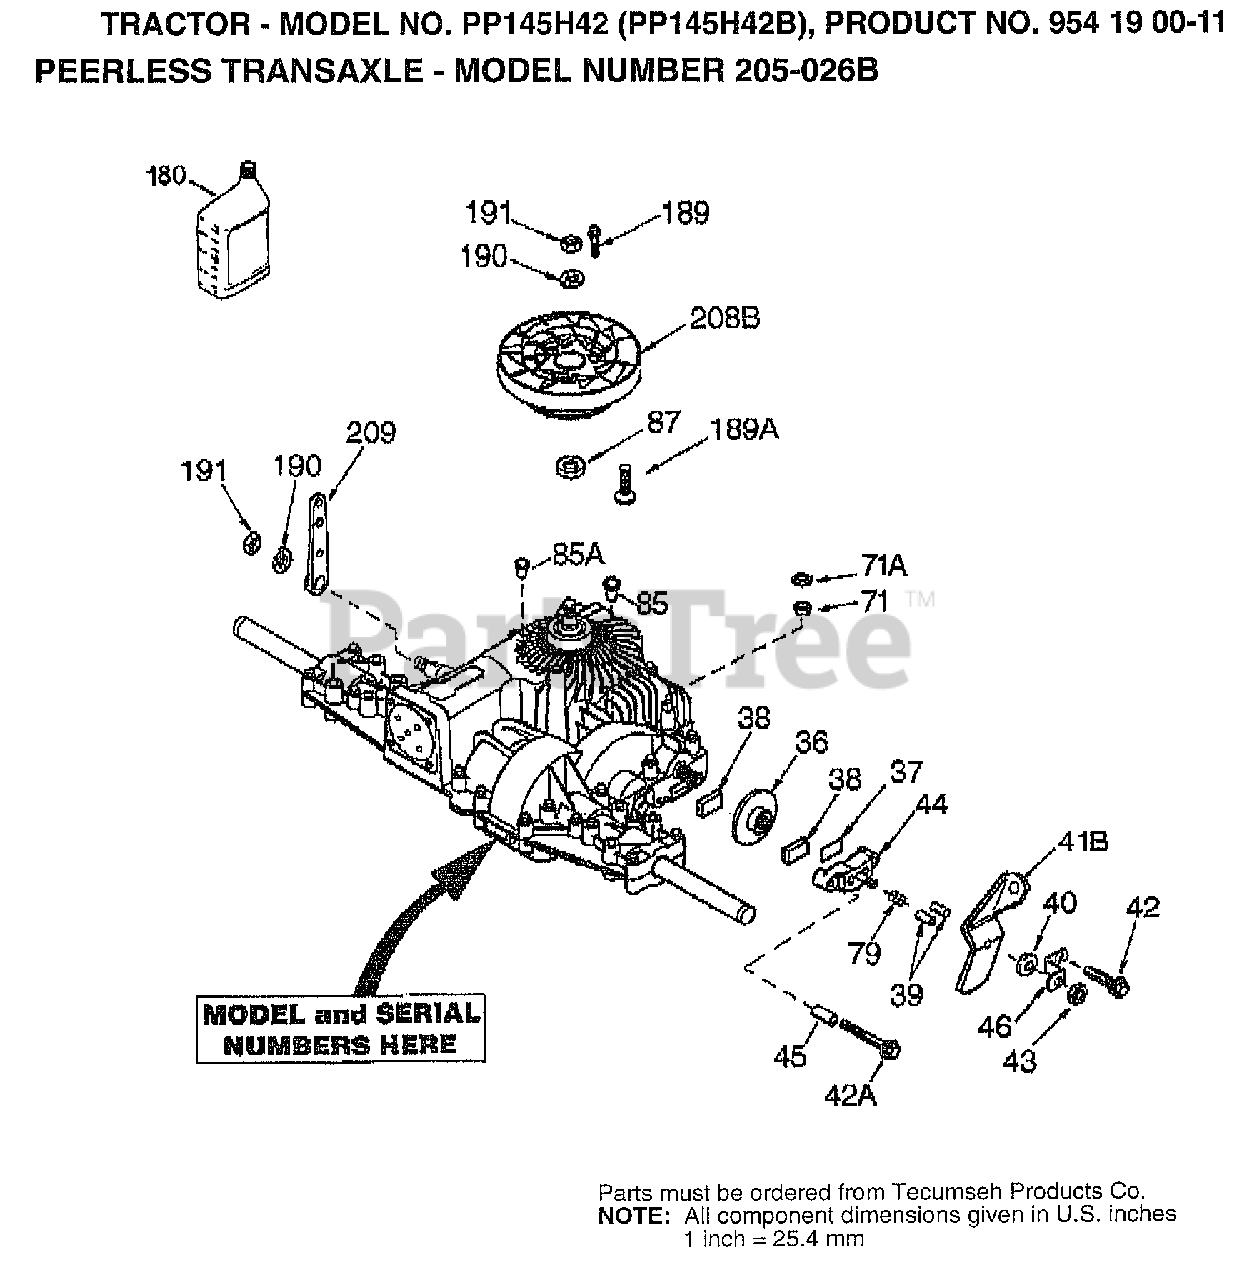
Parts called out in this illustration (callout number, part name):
37	PLATE BRAKE PAD
41B	BRAKE LEVER
42A	SCREW, 1/4-20 X 2-1/4
43	LOCKNUT 5/16-24
44	HOLDER BRAKE PAD
46	BRAKE LEVER BRACKET
71	SEAL SQUARE CUT
85	OIL FILL PLUG
85A	TUBE PLUG, 3/8"
180	GEAR OIL 80W90
189	DRIVE SCREW
208B	FAN/COUPLING
209	CONTROL LEVER
